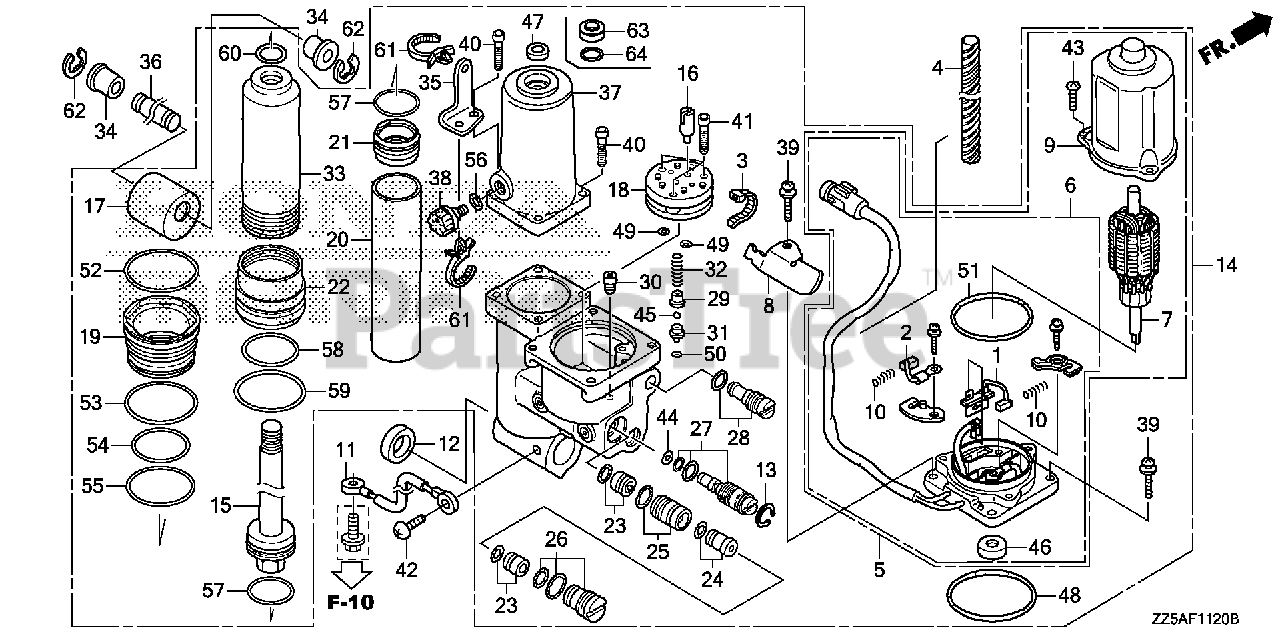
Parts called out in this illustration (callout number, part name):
1	BREAKER ASSY.
2	BRUSH ASSY.
3	BAND (BLACK 3.5X140)
4	TUBE, SPIRAL
5	MOTOR ASSY., POWER TILT
6	BRACKET ASSY.
8	CLAMP, WIRE
10	SPRING, MOTOR
11	WIRE, LEAD (1.5X116MM)
12	SPACER (19.4X6)
13	CIRCLIP (INNER) (16)
14	TRIM-TILT ASSY., POWER
15	ROD, PISTON
16	JOINT, DRIVE
17	METAL, JOINT
19	GUIDE, TUBE (OUTER)
21	PISTON, FREE
22	LOWER TILT CYLINDER
27	VALVE, MANUAL
29	GUIDE, SPRING
30	VALVE, SET
31	SEAT B, VALVE
32	SPRING, VALVE
33	TUBE (OUTER)
34	BUSH, CYLINDER (UPPER)
35	PLATE, SET
36	PIN, CYLINDER (UPPER)
37	TANK, OIL
37	RESERVOIR
38	CAP, OIL TANK
39	SCREW-WASHER
40	BOLT, SOCKET (5X0.8)
41	BOLT, SOCKET
42	SCREW, PAN (6X8)
43	SCREW, PAN (5X20)
44	WASHER, SEAL
45	BALL, STEEL
47	SEAL, WATER
48	O-RING (1.8X69.6)
49	O-RING (1.5X6.5)
50	O-RING (1.5X3.5)
51	O-RING (2.0X55.5)
52	O-RING (2.0X52.5)
53	O-RING (2.0X49.5)
54	O-RING (2.4X41.2)
55	O-RING (2.0X45.5)
56	O-RING (1.8X10.8)
57	O-RING (2.0X28.5)
58	O-RING (2.0X34.5)
59	O-RING (3.5X41.7)
60	O-RING (2.4X15.8)
61	CLIP, HARNESS BAND (145MM) (BLACK)
62	E-RING (10MM)
63	SEAL, WATER
64	O-RING (1.9X15.8)
